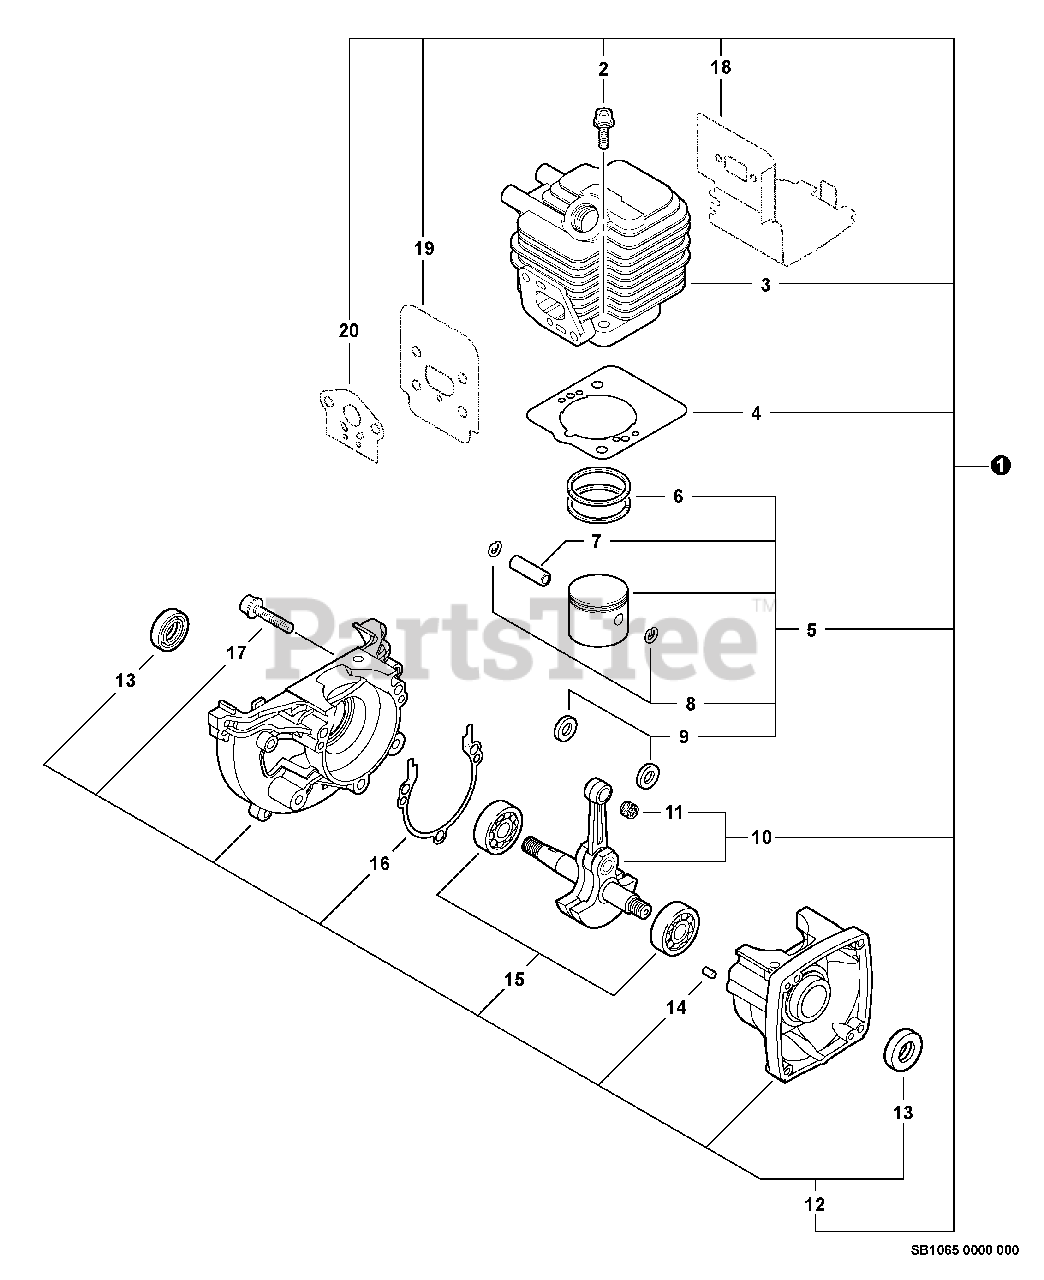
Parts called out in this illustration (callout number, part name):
1	SHORT BLOCK
2	BOLT 5×22
3	CYLINDER
4	GASKET, CYLINDER
5	PISTON KIT
6	RING, PISTON
7	PIN, PISTON 8
8	RING, SNAP
9	WASHER, THRUST
10	CRANKSHAFT ASSY
11	BEARING, NEEDLE 8
12	CRANKCASE KIT
13	SEAL, OIL 12
14	PIN, LOCATING 4
15	BEARING, BALL - 6201 C3
16	GASKET, CRANKCASE
17	BOLT 5×28
18	SHIELD, EXHAUST
19	SHIELD, INTAKE
20	GASKET, INTAKE
